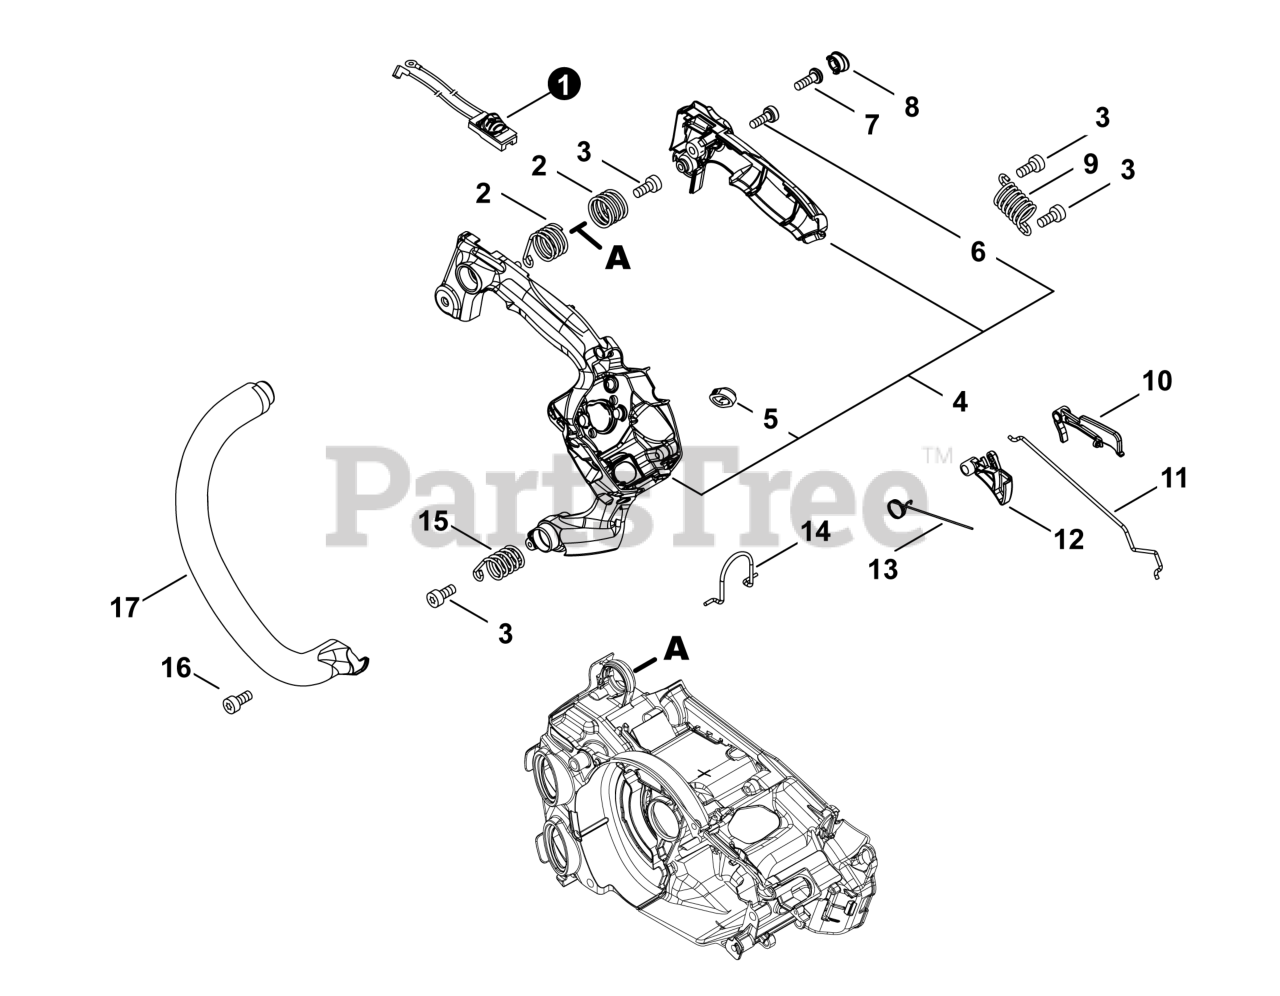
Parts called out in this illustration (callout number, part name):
1	SWITCH, ON-OFF
2	SPRING, COMPRESSION
3	BOLT, TORX 4×12
4	HANDLE SET, REAR
5	GROMMET, NEEDLE
6	BOLT, TORX 4×16
7	BOLT, TORX 5×16
9	SPRING, COMPRESSION
10	LOCKOUT, THROTTLE
11	ROD, THROTTLE
12	CONTROL, THROTTLE
13	SPRING, TORSION
14	RING, HARNESS
15	SPRING, COMPRESSION
16	BOLT, TORX 4×16
17	HANDLE, FRONT
